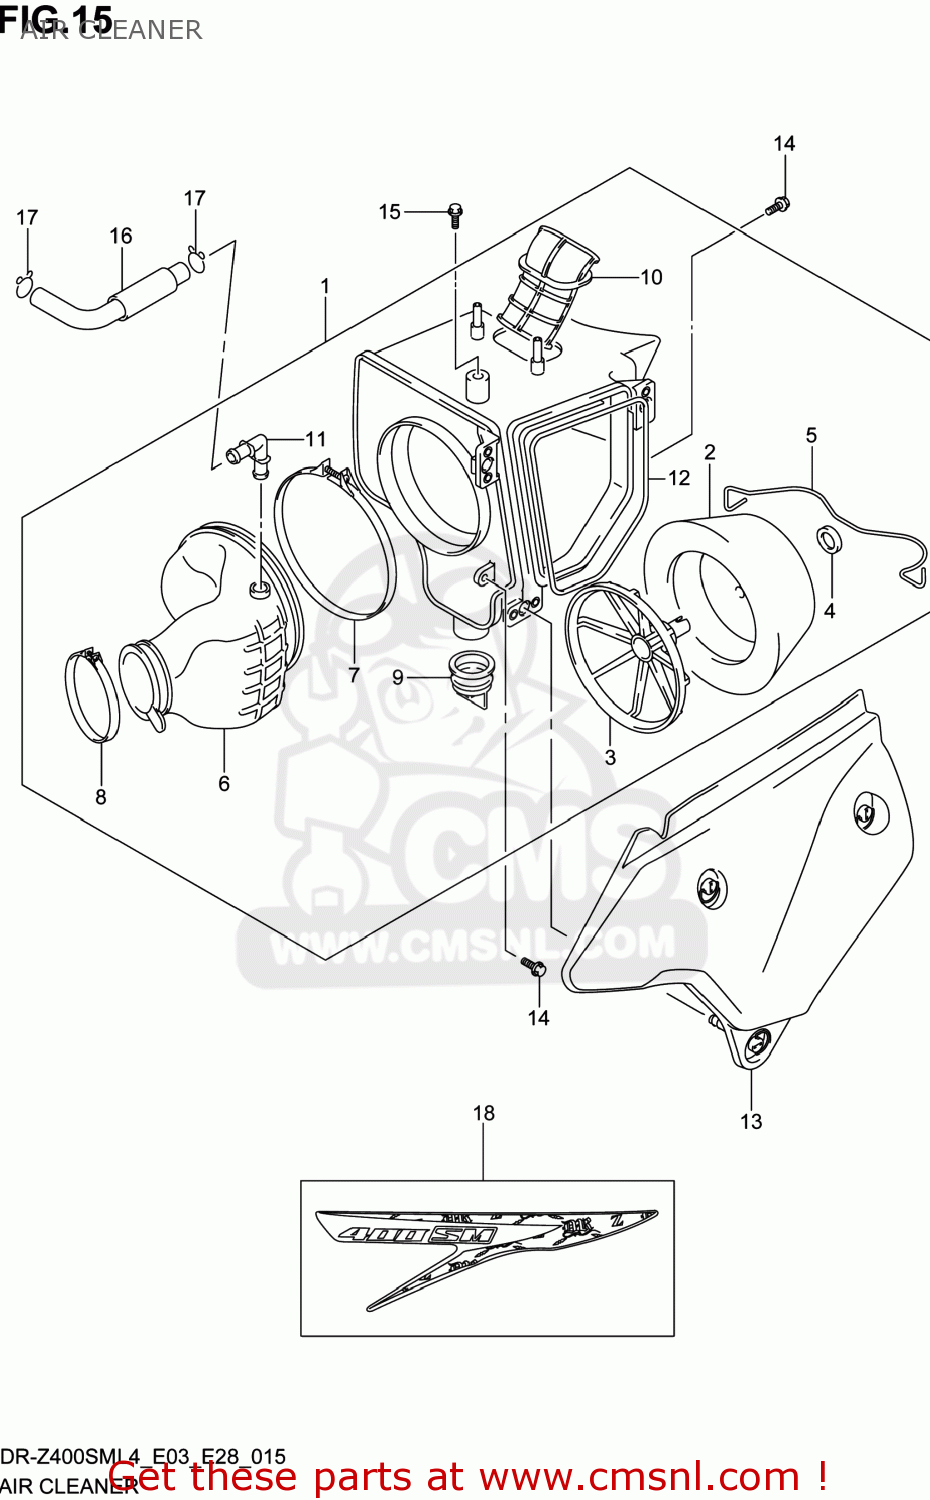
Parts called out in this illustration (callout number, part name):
1	CLEANER,AIR
2	FILTER ASSY
3	HOLDER,FILTER
4	SPACER
5	SPRING
6	TUBE,OUTLET
7	CLAMP
8	CLAMP
9	VALVE
10	TUBE,INLET
11	JOINT
12	GASKET,AIR CLEANER (NAS)
13	CAP COMP,AIR CLEANER
14	BOLT
15	BOLT(6X14.6)
16	TUBE,BREATHER
17	CLIP
18	TAPE,AIR CLNR CAP
